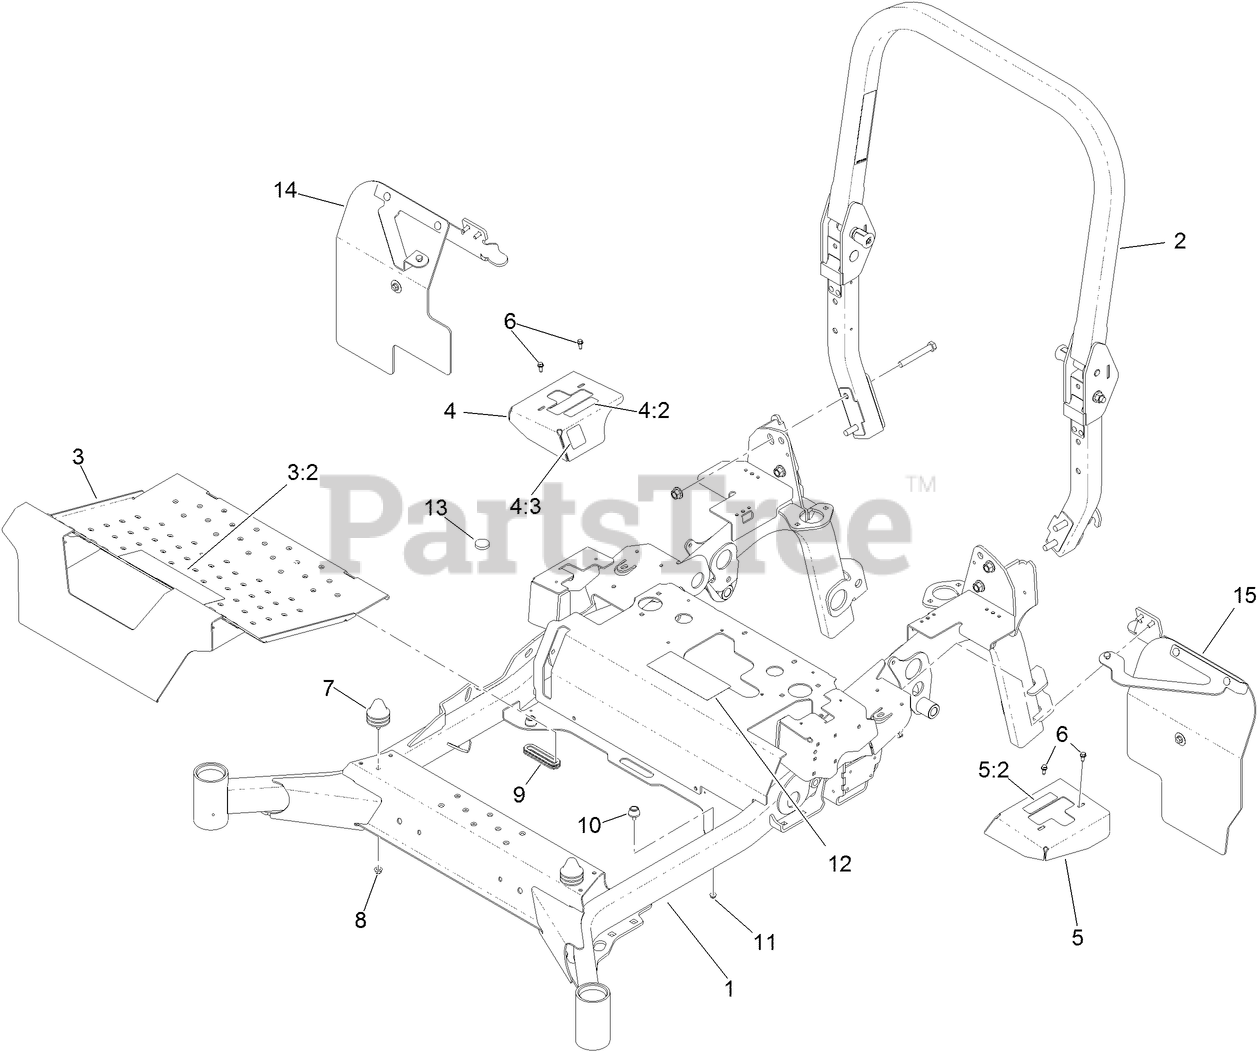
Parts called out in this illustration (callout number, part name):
1	FRAME-MAIN
2	ASM, ROPS-7500D DIESEL
3	PAN-FLOOR
3:2	DECAL-DANGER
4	COVER-MOTION CONTROL, RH
4:2	DECAL-CONTROL, MOTION
4:3	DECAL-PARK BRAKE, CE
5	COVER-MOTION CONTROL, LH
5:2	DECAL-CONTROL, MOTION
6	SCREW-HWH
7	ISOLATOR
8	NUT-HF, NI
9	GROMMET-RUBBER
10	BUMPER-RUBBER
11	NUT-HF
12	DECAL-SERVICE AID
13	BUMPER-PUSH-IN, RUBBER
14	ASM, RH MUD FLAP
15	ASM, LH MUD FLAP
